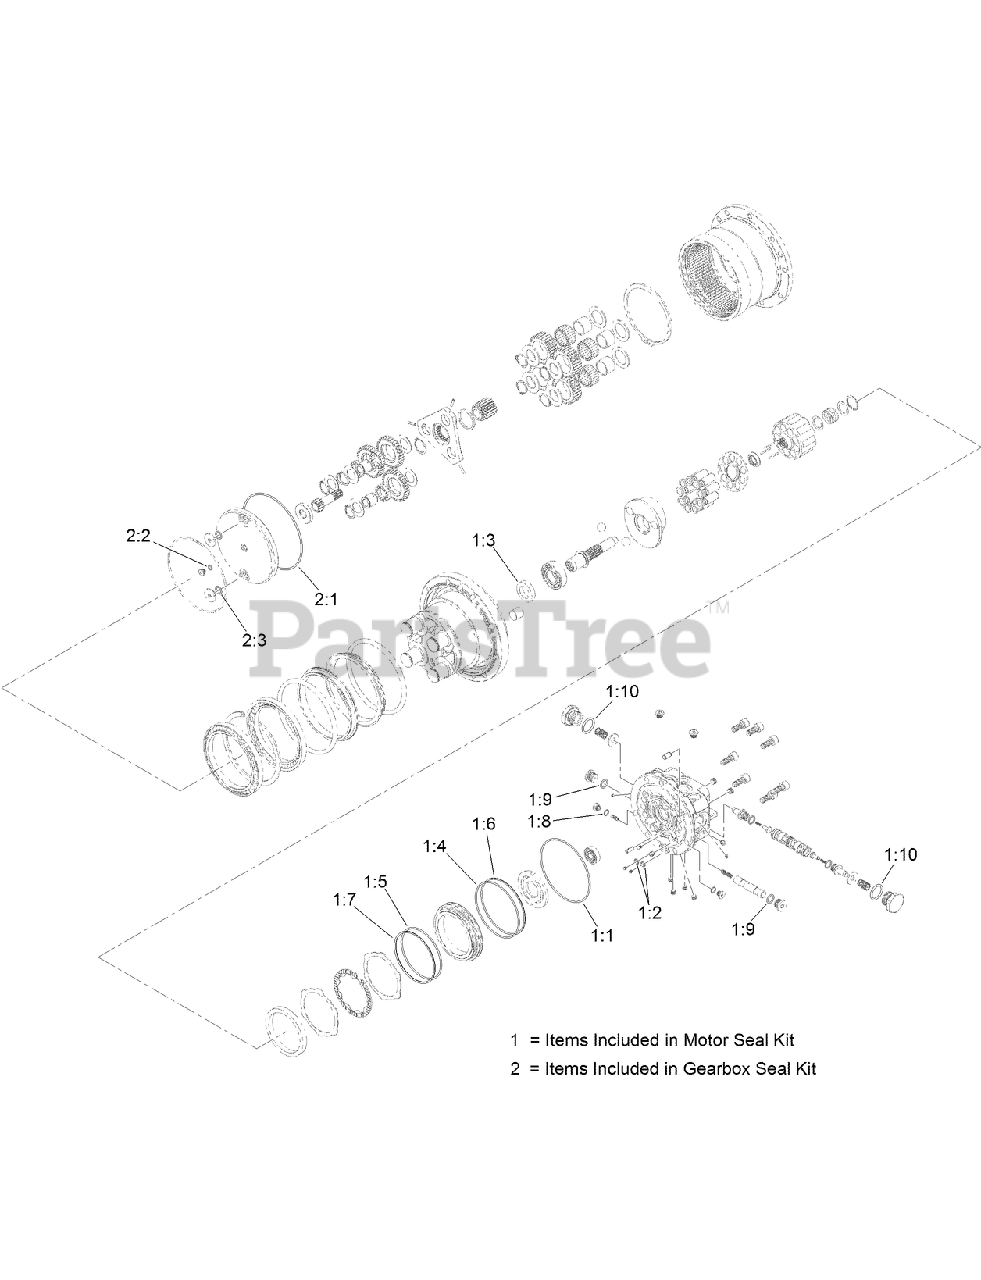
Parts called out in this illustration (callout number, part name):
1	MOTOR SEAL KIT
1:1	O-RING
1:2	O-RING
1:3	Seal-Oil
1:4	O-RING
1:5	O-RING
1:6	Ring-Back Up
1:7	Ring-Back Up
1:8	O-RING
1:9	O-RING
1:10	O-RING
2	GEARBOX SEAL KIT
2:1	O-RING
2:2	O-RING
2:3	O-RING
